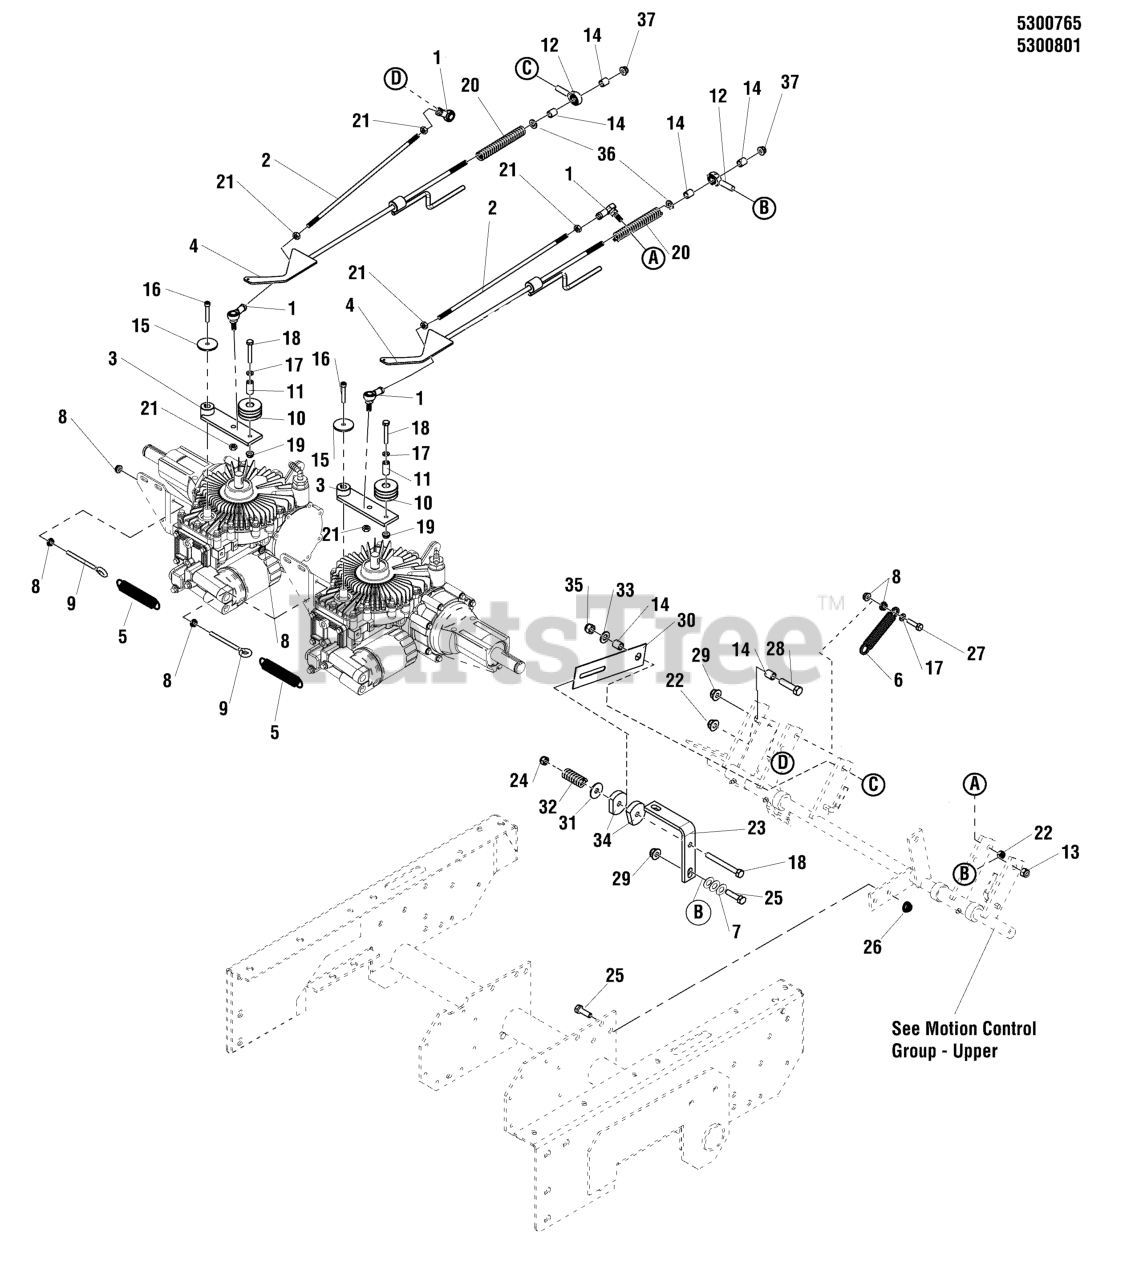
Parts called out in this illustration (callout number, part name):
1	BALL JOINT 5/16-24 RH FEMALE W/STUD, BR
2	ROD, TRANSMISSION REVERSE
3	WELD, STROKE ARM
4	WELD, ROD, TRANSAXLE LINKAGE
5	SPRING, EXTENSION
6	SPRING, EXTENSION
7	WASHER, 3/8 SAE
8	NUT, 1/4-20 HEX SERR. FLANGE
9	EYE BOLT, 1/4-20 X 2.5, 1THRD, .5EYE,CZ
10	ROLLER, SPEED CONTROL
11	SLEEVE, CRUISE CONTROL, ROLLER
12	BALL JOINT, 3/8-24
13	NUT, 3/8-24 HEX NYLON LOCK
14	SPACER, .38 X .50 X .562
15	WASHER, .265 X 1.50 X .109, YZ
16	BOLT, 1/4-20 X 1-1/2" ALLEN HEAD, PATCH
17	WASHER, 1/4 SAE
18	BOLT, 1/4-20 X 1.3/4" GD5
19	NUT, 1/4-20 HEX NYLOCK FLANGE
20	SPRING-COMP, .435ID X 4.75LG X .137WR
21	NUT, 5/16-24 HEX
22	NUT, 5/16-24 HEX NYLON LOCK
23	SUPPORT, DDS ENGINE DECK
24	NUT, 5/16-18 HEX NYLOCK FLANGE
25	BOLT, 3/8-16 X 1" GD5 CZ
26	NUT, 3/8-16 HEX NYLON FLANGE
27	BOLT, 1/4-20 X 1" GD5 CZ
28	BOLT, 3/8-16 X 1-1/2" GD5 CZ
29	NUT, 3/8-16 HEX SERRATED FLANGE
30	PLATE, FRICTION
31	WASHER, 5/16" FENDER
32	SPRING-COMP, .438ID X 1.75LG X .137WR
33	WASHER, 3/8 SAE
34	PAD, BRAKE
35	NUT, 3/8-24 HEX NYLON LOCK
36	WASHER, 5/16" SAE
37	NUT, 5/16-24 HEX NYLOCK FLANGE
